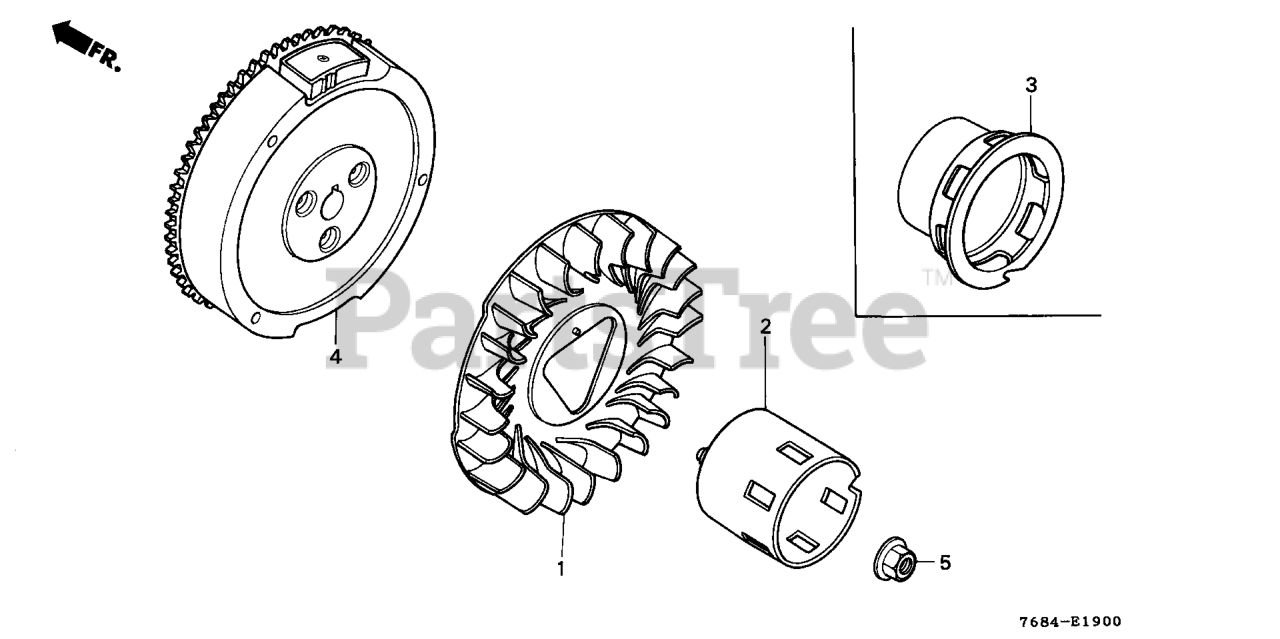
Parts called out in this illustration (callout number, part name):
1	FAN, COOLING
2	PULLEY, STARTER
4	FLYWHEEL (LAMP)
5	NUT, SPECIAL (16MM) (1)
